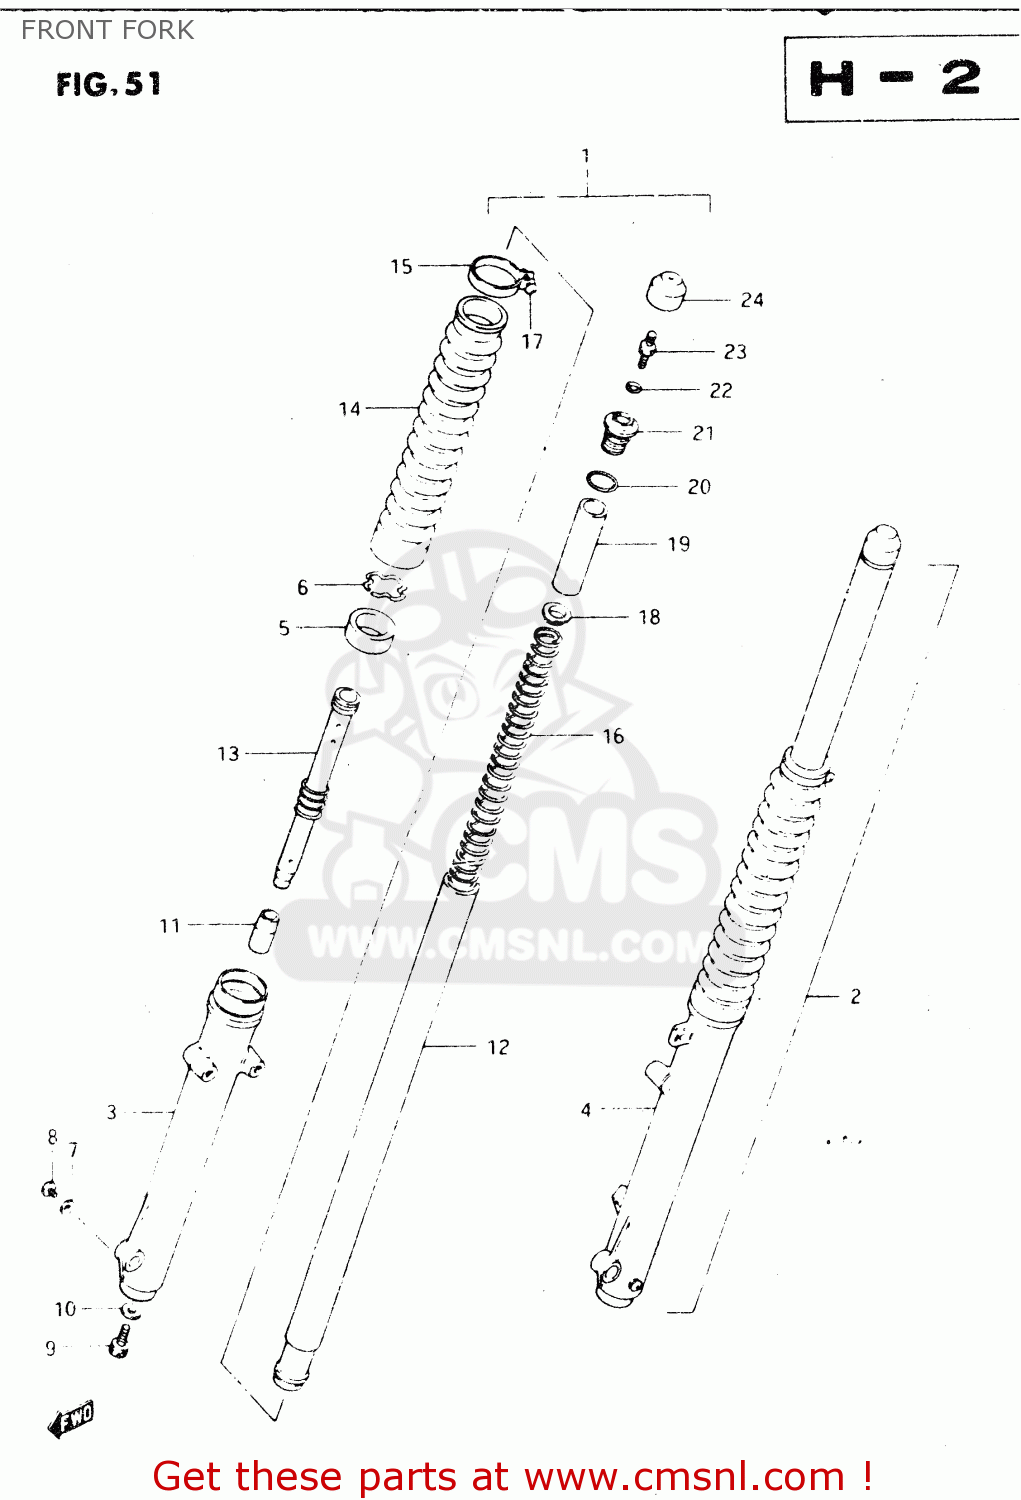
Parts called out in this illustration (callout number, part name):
1	DAMPER ASSEMBLY,RIGHT
2	DAMPER ASSEMBLY,LEFT
3	TUBE,FORK,OUTER,RIGHT
4	TUBE,FORK,LEFT,OUTER
5	OIL SEAL,FRONT FORK
6	7
7	GASKET,DRAIN,PLUG (NAS)
8	SCREW
9	BOLT,FORK CYLINDER(10X25)
10	GASKET (NAS)
11	PIECE,OIL LOCK
12	TUBE,INNER
13	CYLINDER,FRONT FORK
14	BOOT
15	BAND,BOOT
16	SPRING
17	SCREW
18	GUIDE,FRONT FORK SPRING C
19	COLLAR,SPRING
20	O RING
21	CAP,FORK INNER TUBE
22	O-RING
23	VALVE,FRONT FORK AIR
24	CAP
